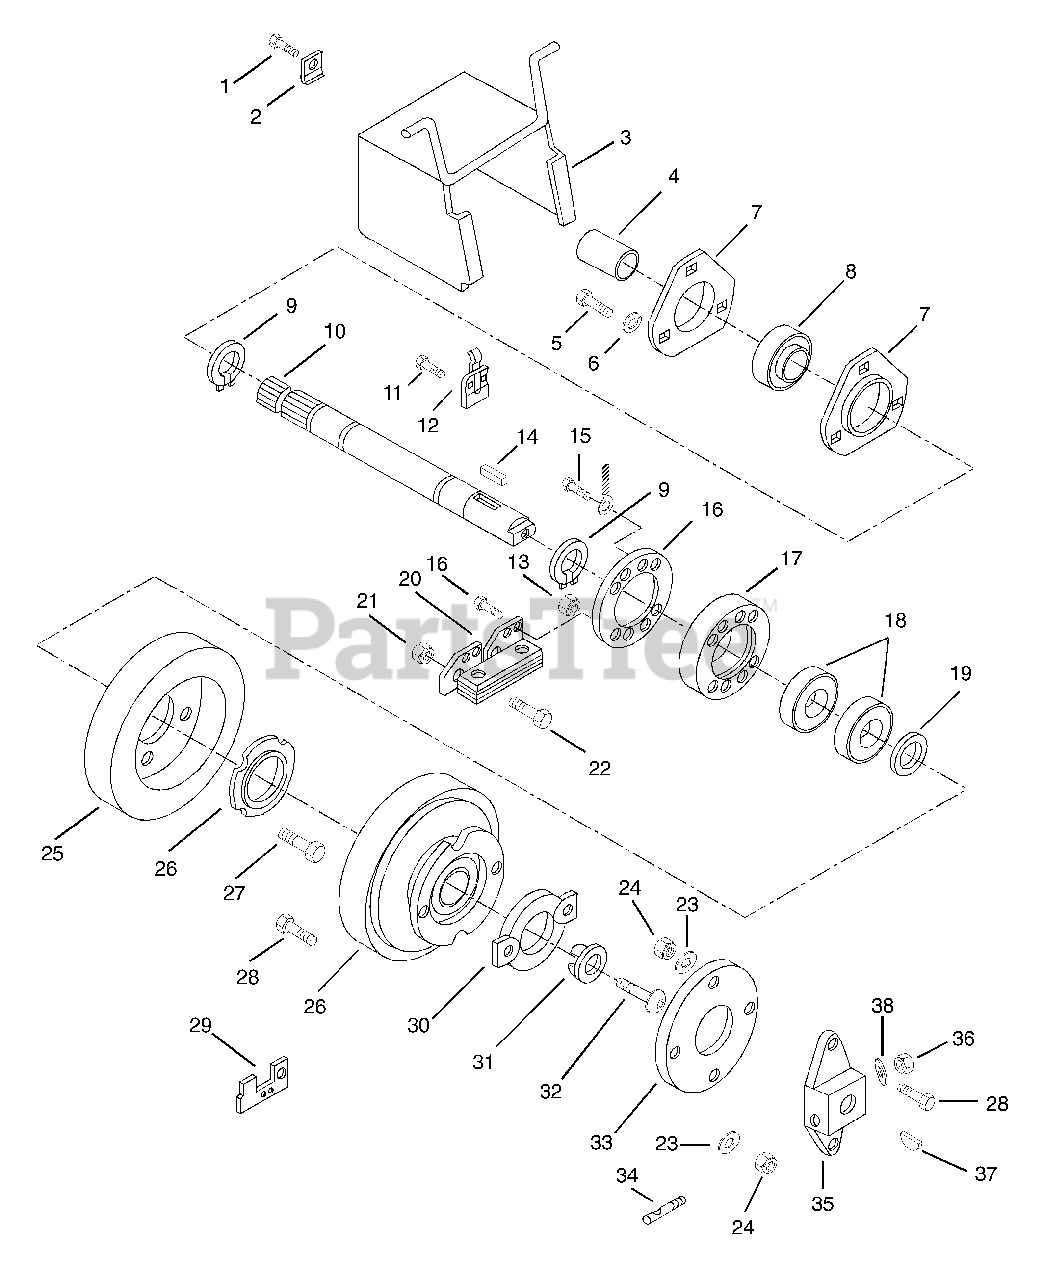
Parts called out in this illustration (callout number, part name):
1	@SCR-TAP .25-20X.50 HWH TR YWZ
3	PTO SHIELD
4	SHAFT COVER
5	@BLT-HEX .31-18X.75 GR5 YWZC
6	WSHR-LK .312X.097 HVY YWZC
7	BEARING FLANGE
8	BRG/W COLLAR 1.0 X 2.047 X.844
9	RG-RTNG-EXT 1.00X.078
11	@SCR-TAP 10-24X.375 HWH YZ TR
12	SNAP FASTENER
13	NUT-LK-DUAL FACE 10-24 YWZC
14	KEY-SQ .25X1.0X.25 SAE 8630
15	SCR-TAP 10-24X.75 HWH TR YWZC
17	BEARING MOUNT
18	BRG-BALL 1.0X2.0X.56 (1641)
19	WSHR-FL-STL 1.031X1.375X.055YZ
20	TORQUE BRACKET ASSEMBLY
21	@NUT-HEX .31-18 YWZC
22	@BLT-HEX .31-18X1.50 GR5 YWZC
23	@WSHR-FL-STL.344X.688X.065YWZC
24	@NUT-LK-CTR .31-18 YWZC
25	ELECTRIC CLUTCH
26	BEARING FLANGE
27	SCR-MCH 10-24X1.25 SL PAN YWZC
28	BOLT-HEX.31-18X.875 YWZC GR5
29	CONNECTOR MOUNTING CLIP
30	PILOT PLATE
31	RETAINER
32	BLT-BTHD .38-16X1.25 GR5
33	SPACER COUPLING
34	LOCK STUD
35	COUPLING
36	@NUT-HEX .38-16 YWZC
37	KEY-WDRF .188X.75X.313 SAE 9
38	@WSHR-LK .38X.094 REG YWZC
